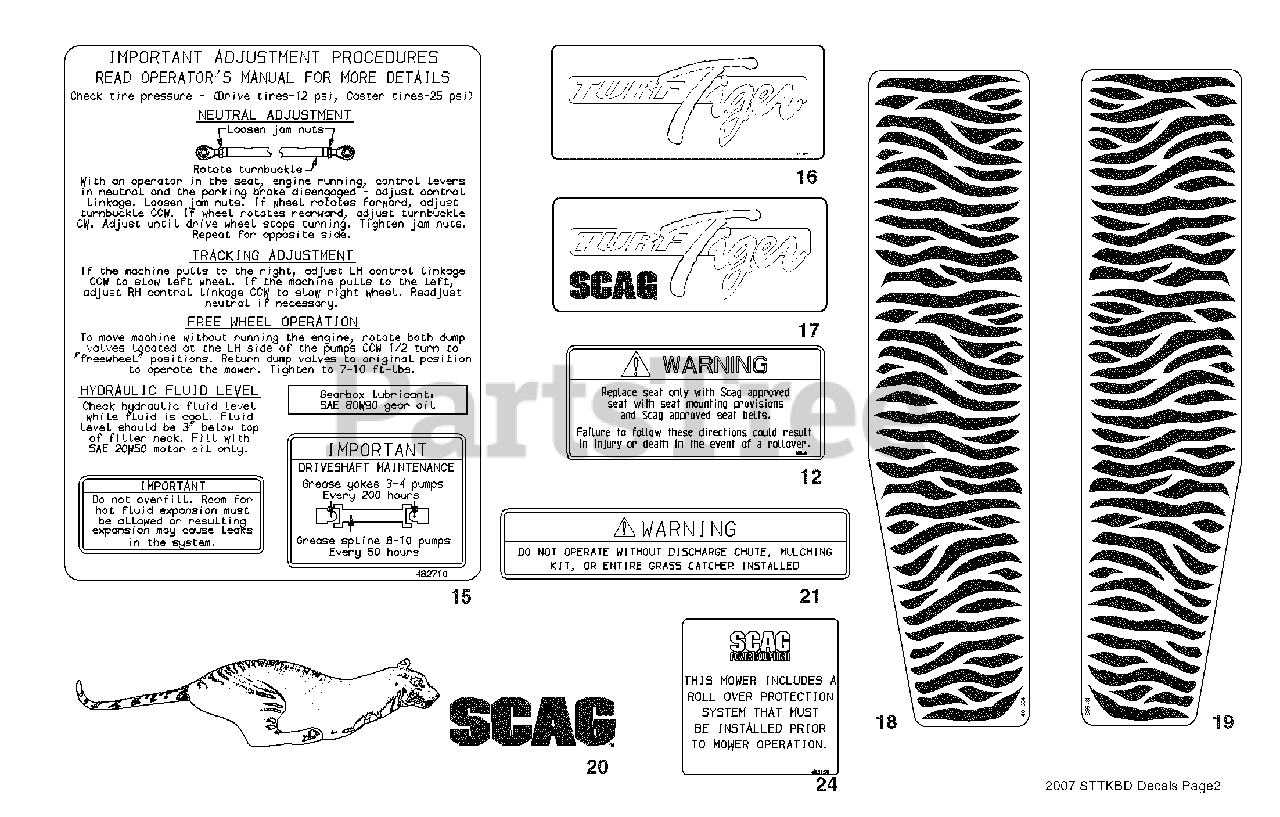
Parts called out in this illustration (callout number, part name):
12	Decal, Seat Replacement
15	Decal, Seat Support
16	Decal, Turf Tiger
17	Decal, Turf Tiger
18	Decal, Stripes-RH
19	Decal, Stripes-LH
20	Decal, Tiger
21	Decal, Warning
24	Decal, ROPS
